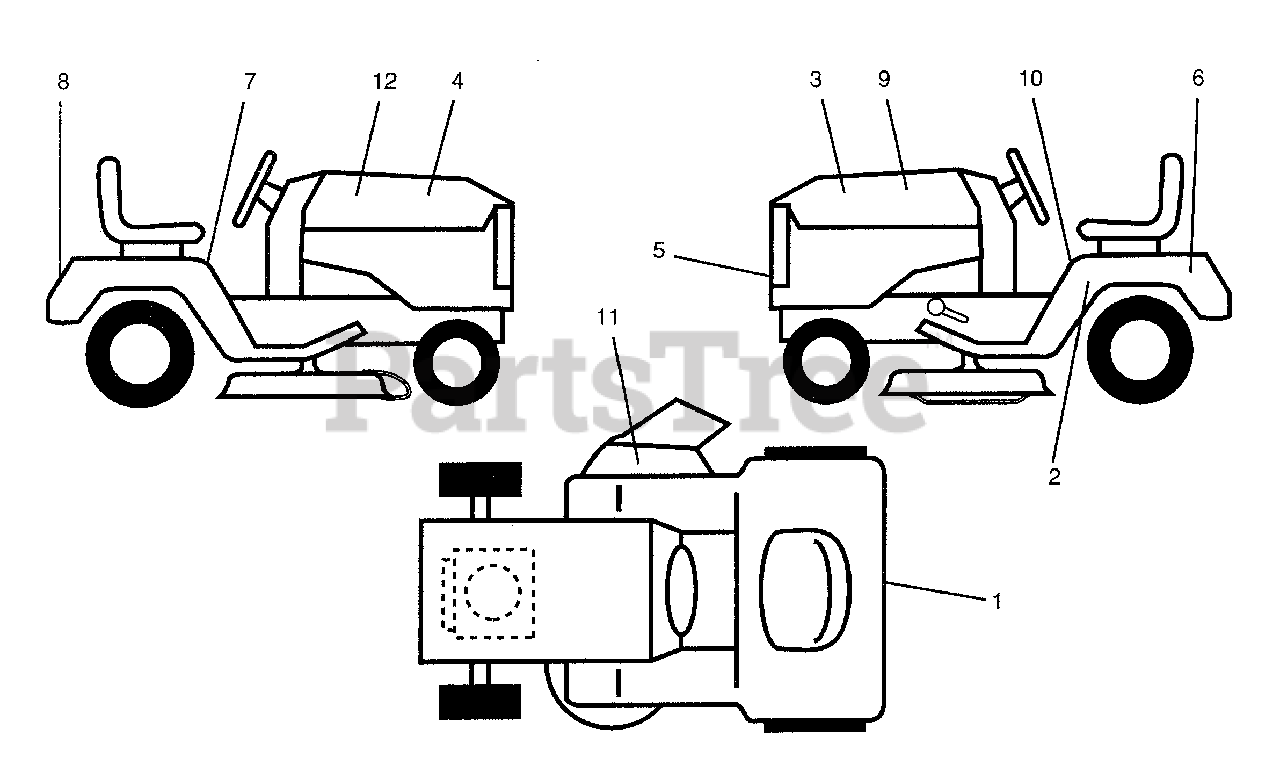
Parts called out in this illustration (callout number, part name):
1	Decal, USA, White
2	Decal, Indicator
3	Decal, Hood, L.H.
4	Decal, Hood, R.H.
5	Decal, Logo, Grill
6	Decal, Caution, Battery
7	Decal, Instruction, Warning,
8	Decal, Logo, Fender
9	Decal, Hood, Insert L.H.
10	Decal Caution Fender
11	Decal, Warning
12	Decal, Hood, Insert, R.H.
CER38	Bagger
